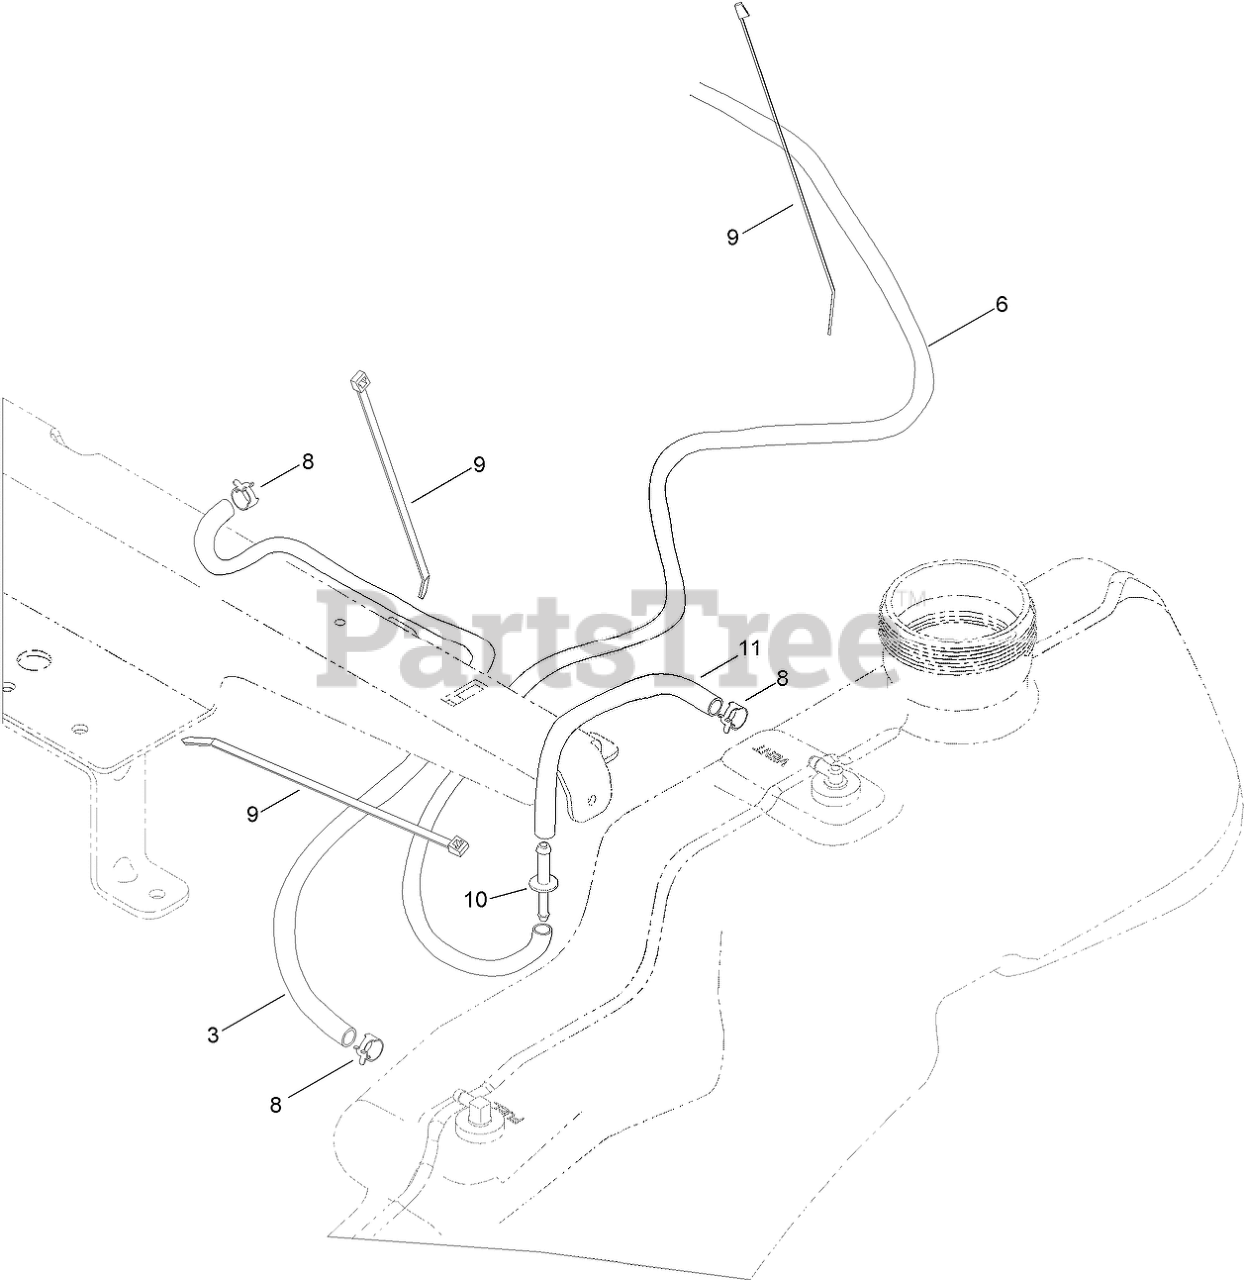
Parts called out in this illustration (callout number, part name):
3	HOSE-FUEL
6	HOSE-FUEL
8	CLAMP-HOSE
9	TIE-CABLE
10	ADAPTOR-ORIFICE
11	HOSE-FUEL
